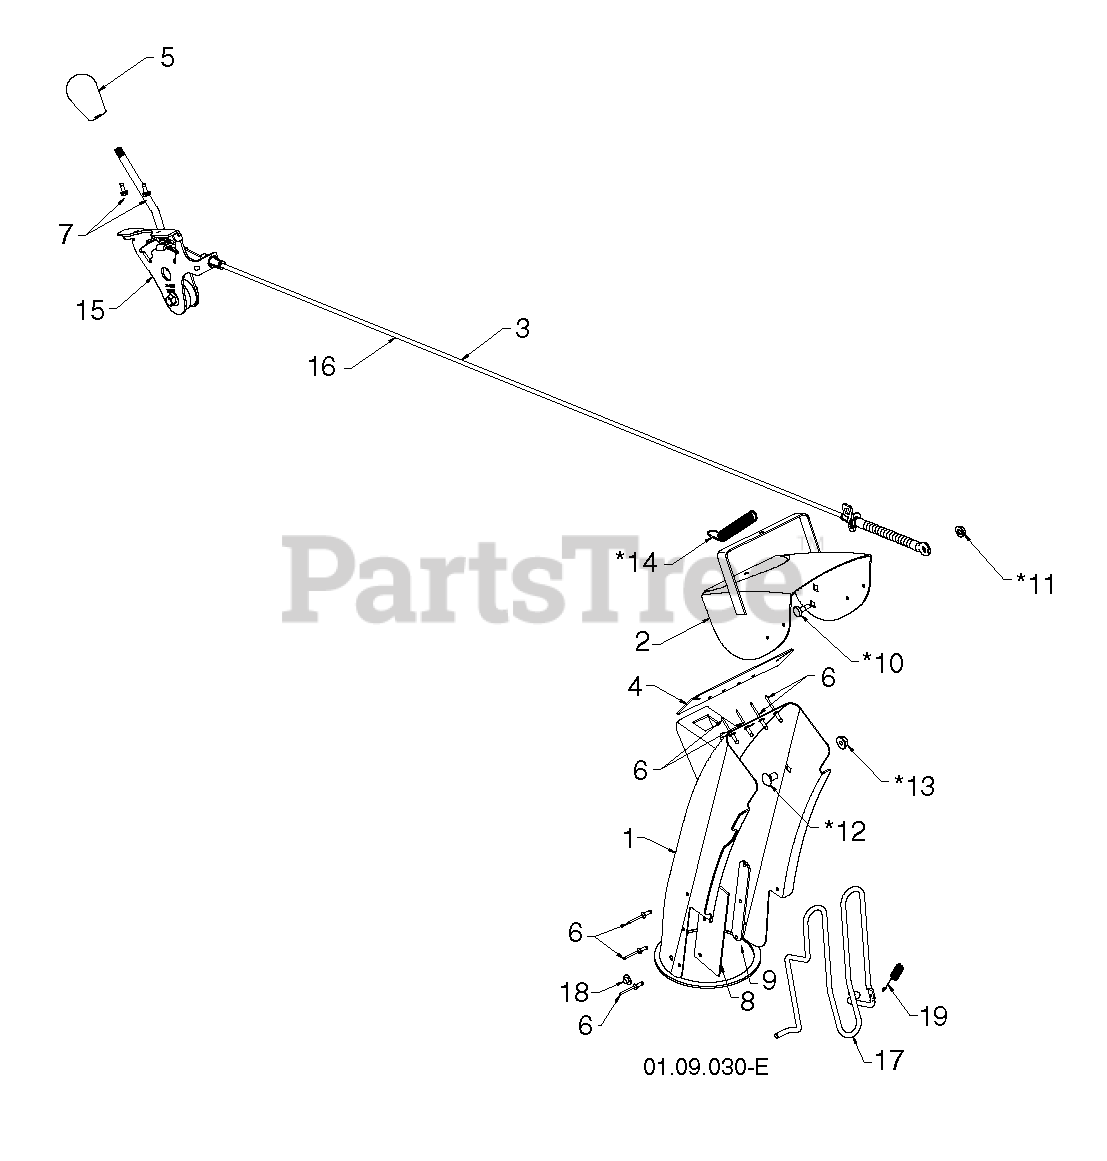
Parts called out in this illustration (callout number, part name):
1	ASM.CHUTE/DEFLECTOR.668
3	CONTROL.ASM.DEFLEC.BLK.BOWDEN
5	KNOB.OVERMOLD.DS.HUSQVARNA/BLK
10	BOLT, SHOULDER
11	NUT.HEX.FLANGE.1/4
12	BOLT CAR BLK 5/16-18 X 5/8
13	LOCKNUT-FLANGE 5/16-18
14	SPRING.DEFLECTOR.REM.CHUTE
15	RP CNTRL.HEAD.ASSEM.DEFLECTOR
16	RP CABLE.DEFLECTOR.CONTRL.BOWD
17	ROD.GUARD.CHUTE (2 2)
18	NUT
19	SPRING.CHUTE.GUARD
